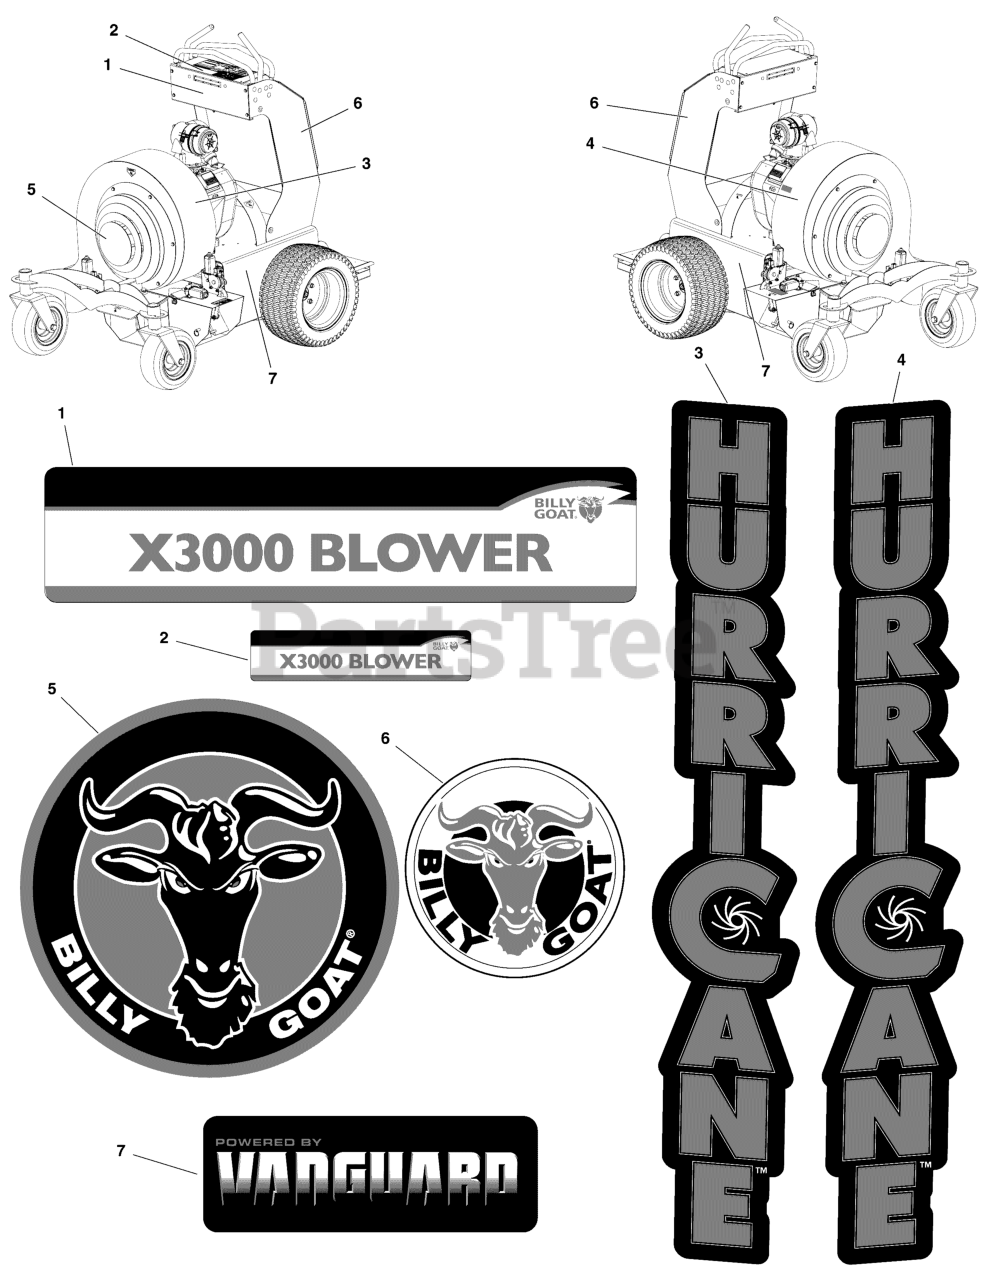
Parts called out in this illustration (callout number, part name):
1	DECAL, X3000 BADGE
2	DECAL, X3000 TOP PANEL
3	DECAL, X3000 HURRICANE_VERT, LH
4	DECAL, X3000 HURRICANE_VERT, RH
5	DECAL, X3000 FRONT LOGO
6	LABEL, PRODUCT DECAL LG CIRCLE
7	DECAL, BRAND
